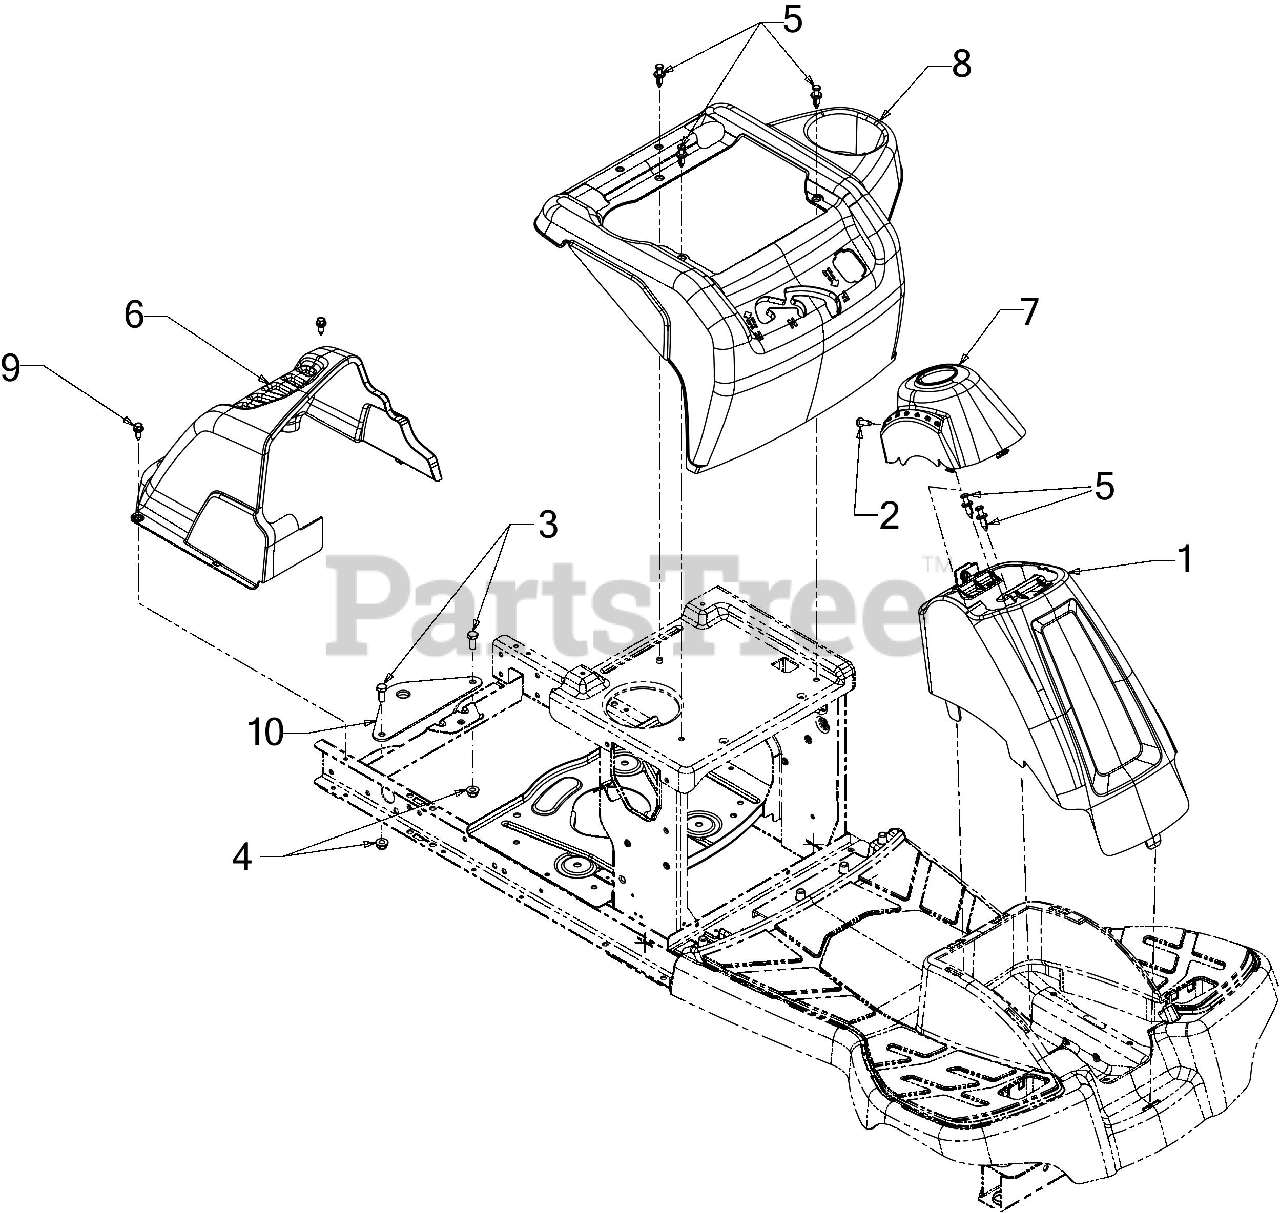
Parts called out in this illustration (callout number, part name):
1	COLUMN COVER ASSEMBLY (CRAFTSMAN RED)
2	SCREW 1/4-20X.75
3	SCREW 5/16-18 x .75 GR5
4	FLANGE LOCK NUT 5/16-18
5	PLASTIC RIVET
6	DRIVE COVER
7	STEERING COLUMN CAP (SEARS RED)
8	FENDER
9	SHOULDER SCREW
10	HITCH PLATE
